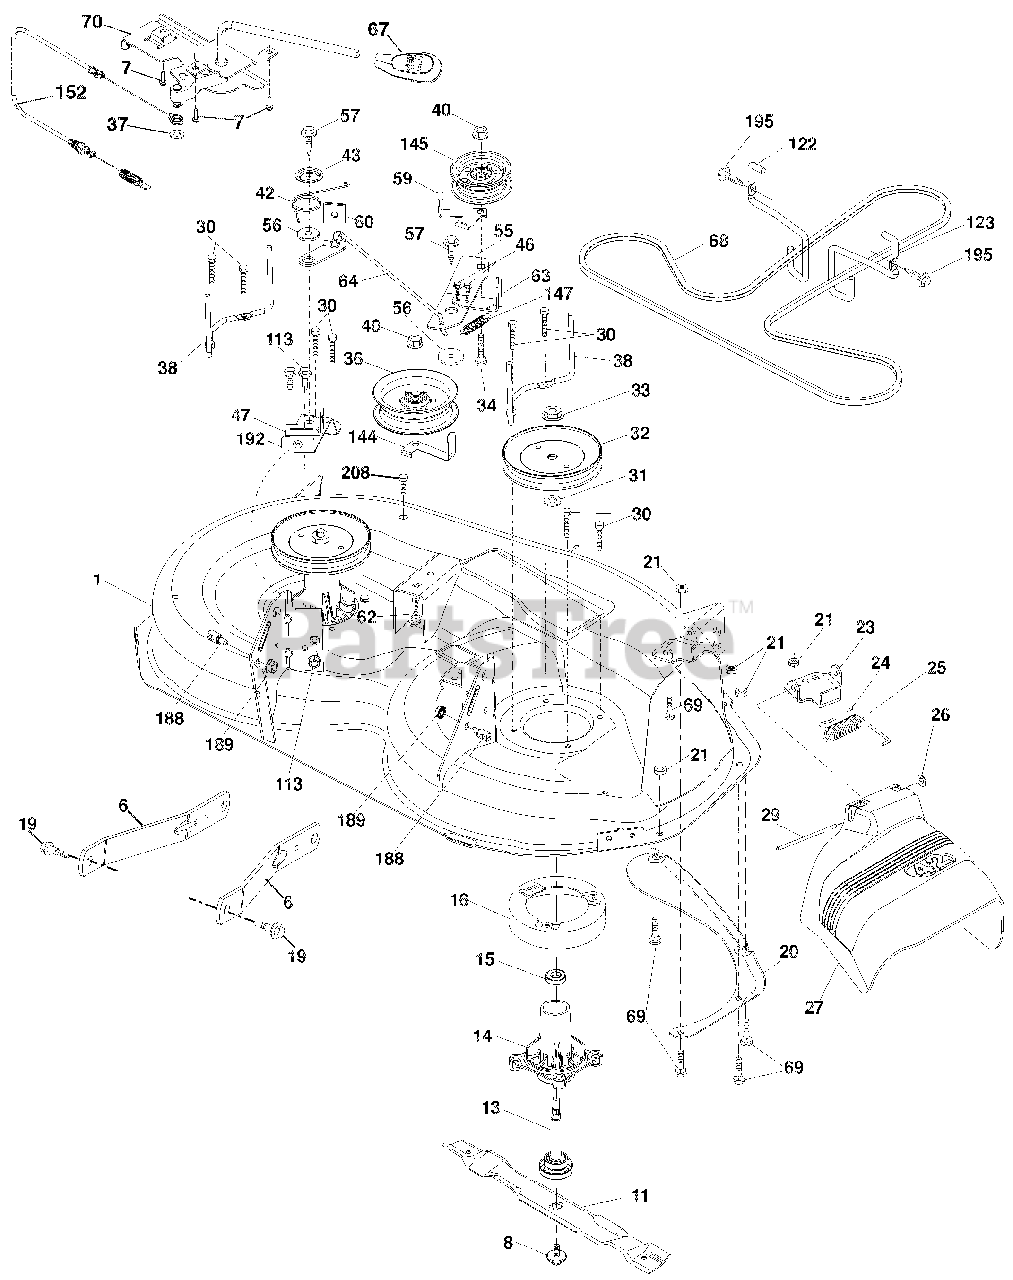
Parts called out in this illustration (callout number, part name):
1	DECK.WELDMENT.42"N/GWB
1	DECK.SVC.42"HP.CC.NGWB.TX.431
6	ARM.SUSPENSION.MOWER.REAR.LD
8	BOLT/WASHER ASM.7/16-20.UNF
11	BLADE.MOWER.42"HI LIFT PREMIUM
13	SHAFT ASM.MNDRL.N/GREASEABLE38
14	HOUSING.MANDREL.4PT.SERVICE
15	BEARING.BALL.MANDREL
16	STRIPPER.MANDREL.DECK
19	BOLT.SHOULDER
20	BAFFLE.VORTEX.42.STD/HEAVY DTY
21	Nut, Hex, Crownlock 5/16-18
23	BRACKET.DEFLECTOR.38/42"2005
24	CAP.SLEEVE..80X.112.BLK.MOWER
25	SPRING.TORSION.DFL.38/42/46.GR
26	NUT.PUSH.PHOS.& OIL
27	SHIELD.DEFLECTOR.MOWER 42"BLK
29	ROD.HINGE.42/46"
30	SCREW.THD ROLL.DOD PT.HEX
31	WASHER.SPACER.MANDREL
32	PULLEY.MANDREL.5.438 PD.42"
32	MANDREL ASM.SUB.N-GRS.4 BOLT
32	pulley/nut/washer and blade bolt/washers not included)
33	NUT.FLANGE.LOCK.TOP
34	BOLT.CARR.SH.3/8-16X1-1/2.GR5
36	PULLEY.IDLER.4.50.RAW
37	WASHER.13/32 X 13/16 X 16 GA.
38	KEEPER.BELT.LH.MANDREL.42/46"
40	Nut, Hex, Flangelock 3/8-16
42	SPRING.TORSION.BRAKE
43	SPRING.TORSION.RETAINER
46	SCREW.THD.ROLL.1/4-20 X 5/8
47	BRACKET.CLUTCH.CABLE
55	IDLER.ARM
56	SPACER.RETAINER
57	SCREW.3/8-16X1.SMGML.TAP/R.BLK
59	GUARD.TUV.IDLER
60	ARM.BRAKE.MOWER.42"
62	BOLT.RD.HD.SQ.NK.3/8-16UNC X 2
63	ARM.BRAKE.MOWER
64	LINKAGE.BRAKE
67	HANDLE.CLUTCH.CABLE.LT TEX.428
68	BELT.DRIVE.100.97"
69	BOLT.RDHD.SQNK.5/16-18 X 5/8
70	CLUTCH ASM.MANUAL.LT.TEX
113	BOLT.5/16-18HEX.WHS.HD.LCKSERR
122	KEEPER.BELT.ENGINE.LH.LT.TEX
123	KEEPER.BELT.ENGINE.RH.LT.TEX
144	KEEPER.BELT.MOWER
145	PULLEY.IDLER 48"PRIMARY
147	SPRING.RETURN
152	CABLE.CLUTCH.MANUAL.W/SPR.
188	STUD.FASTNER.W/'D'ANTI-ROTATIO
189	Nut, Lock Hex Flange 5/16-18 u
192	BRACKET.BRAKE.STAND.LH
195	SCREW.HEXWSH THDR3/8-16X3/4.BL
208	SCREW.THDROL.3/8-16X1/2.TYT.BL
